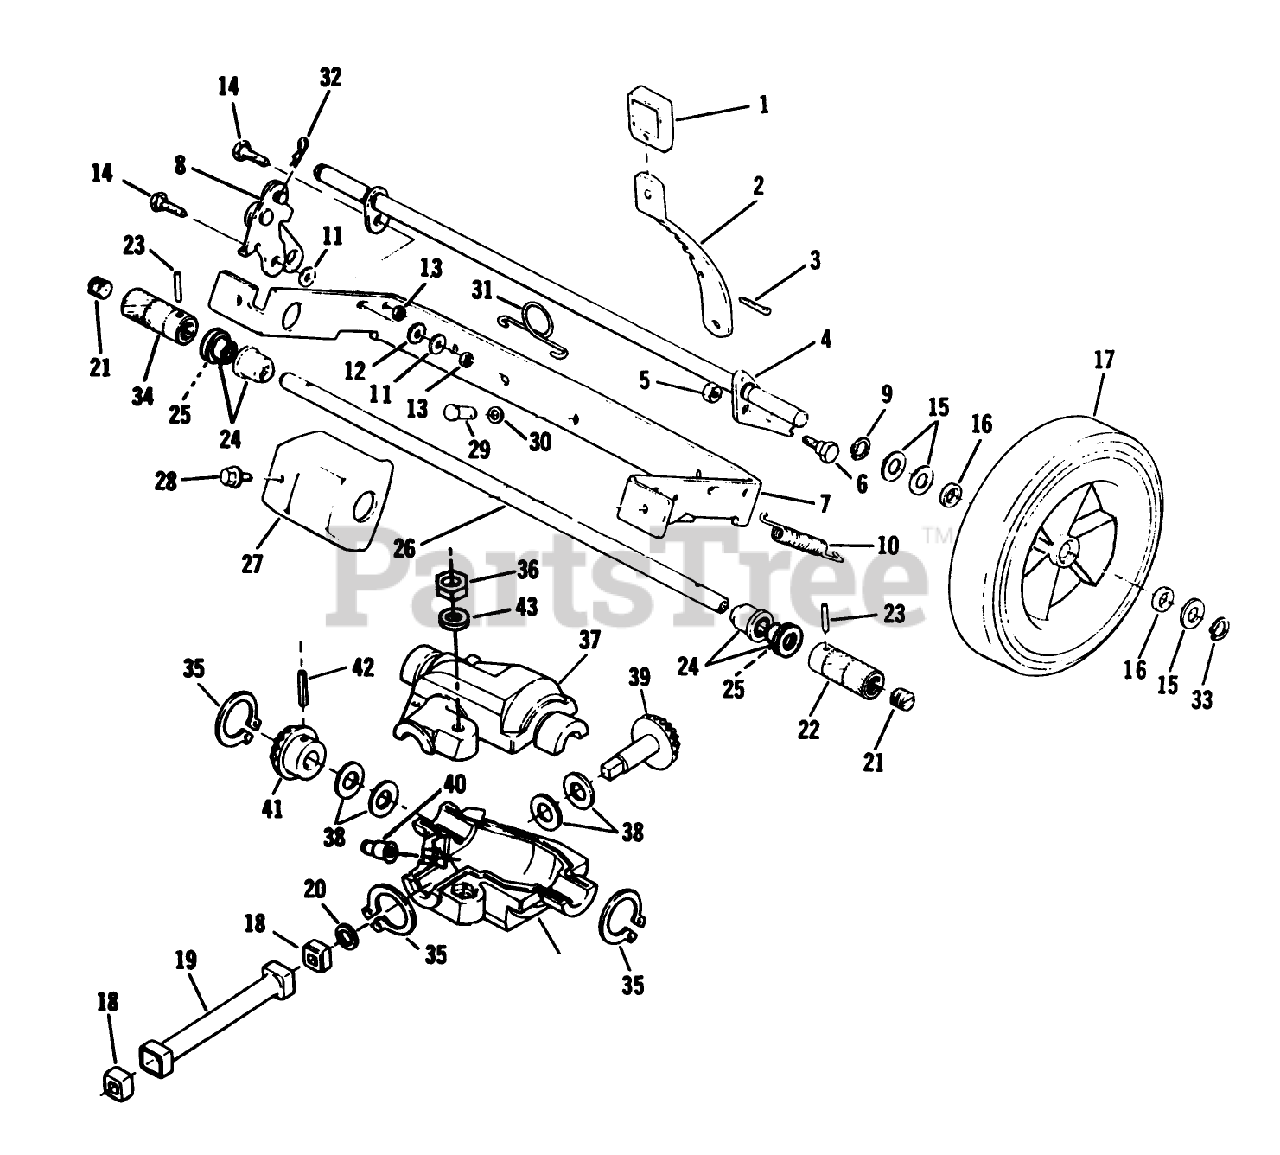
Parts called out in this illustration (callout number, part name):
1	KNOB
2	LEVER
5	LOCKNUT E
6	BOLT RB&W
7	BRK-21" AXLE
9	RET RING
10	SPRING
11	WASHER S
13	STOP NUT
14	BOLT RB&W
15	SPACER
16	WASHER
17	WHEEL & TIRE KIT
18	BUSHING
20	O-RING
21	GREASE PLUG
22	ROLLER (LEFT) VS
22	ROLLER-LH
24	SLEEVE &BEARING AY
25	P/M Bearing
26	DRIVE SHFT TAG AY
27	GUARD
29	PIN
30	WASHER SPRING LAR
31	SPRING N.A.S
33	RET RING
34	ROLLER (RIGHT) VS
34	ROLLER-RH
36	LOCKNUT E
37	GEARCASE AY-SERV
38	THRUST WASHER
39	GEAR BEST
40	ZERK FITTING
41	GEAR ADVANCE
42	ROLL PIN
43	WASHER F
